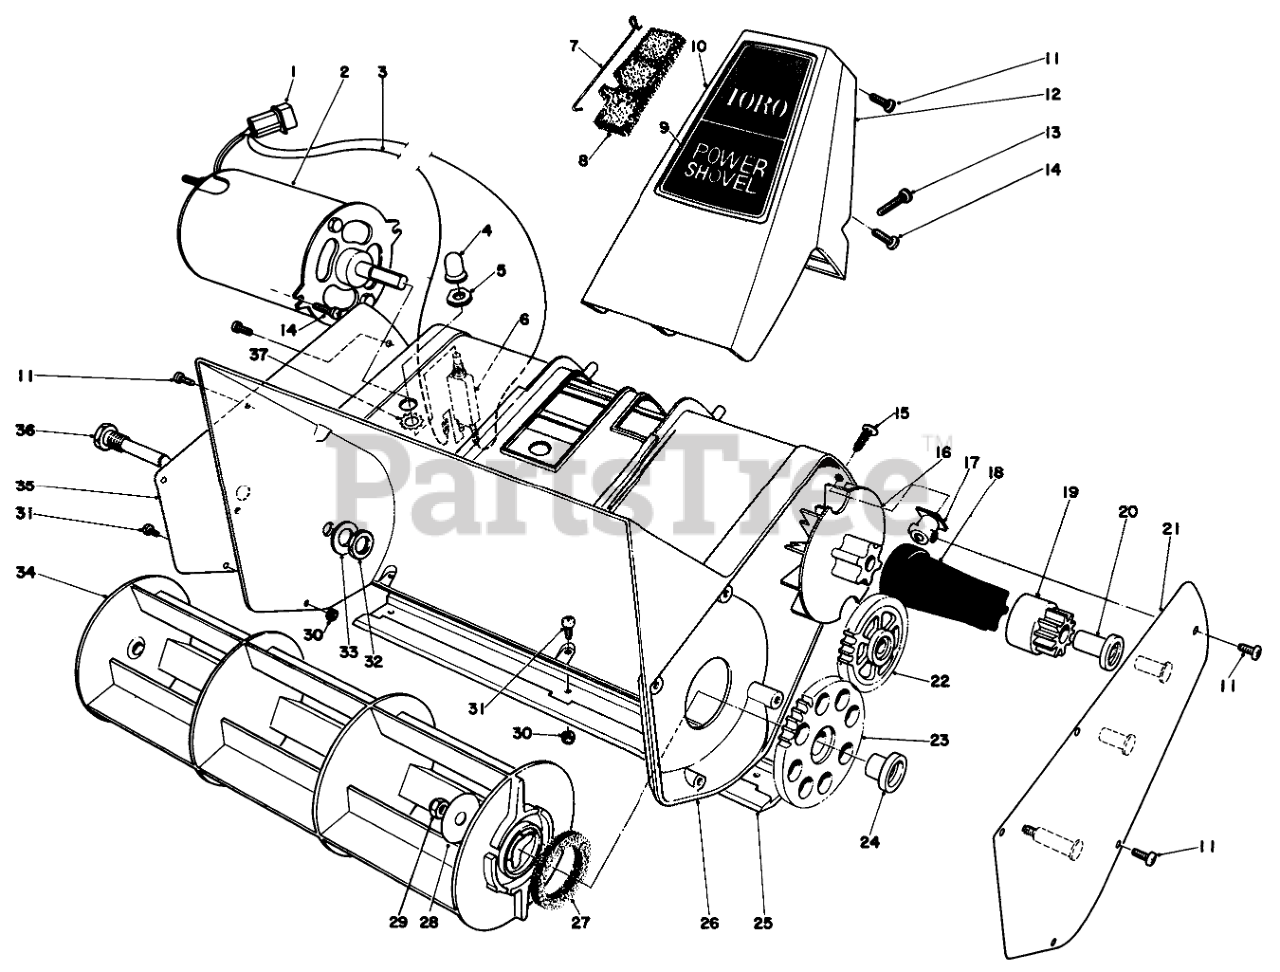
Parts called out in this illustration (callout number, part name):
1	Pin Housing
2	Motor
3	WIRE ASS'Y
4	Circuit Breaker Seal
5	Hex Nut
6	Circuit Breaker (Incl. Ref. #5)
7	RETAINER - FILTER
8	FOAM FILTER
9	HANDLE SUPT DECAL
10	HANDLE SUPPORT, FRONT
11	SCREW-PPH
12	Handle Support-Back
13	SCREW-PPH
14	SCREW-PPH
15	XMAS TREE FASTENER
16	FAN, POWER SHOVEL
17	MTG BLOCK
18	DRIVE COUPLING
19	Drive Gear (Incl. Ref. #20)
20	BUSHING, DRIVE GEAR
21	Gear Carrier
22	Idler Gear
23	Rotor Gear (Incl. Ref. #24)
24	BUSHING, ROTOR GEAR
25	Scraper
26	Housing
27	FELT WASHER
28	ROTOR WASHER
29	NUT-LOCK, NI
30	NUT-LOCK
31	SCREW-PPH
32	3/8 24 JAM NUT
33	WASHER-FLAT
34	ROTOR
35	RT. SIDE COVER (RAW)
36	ROTOR PIN
37	WASHER-LOCK/EXT
